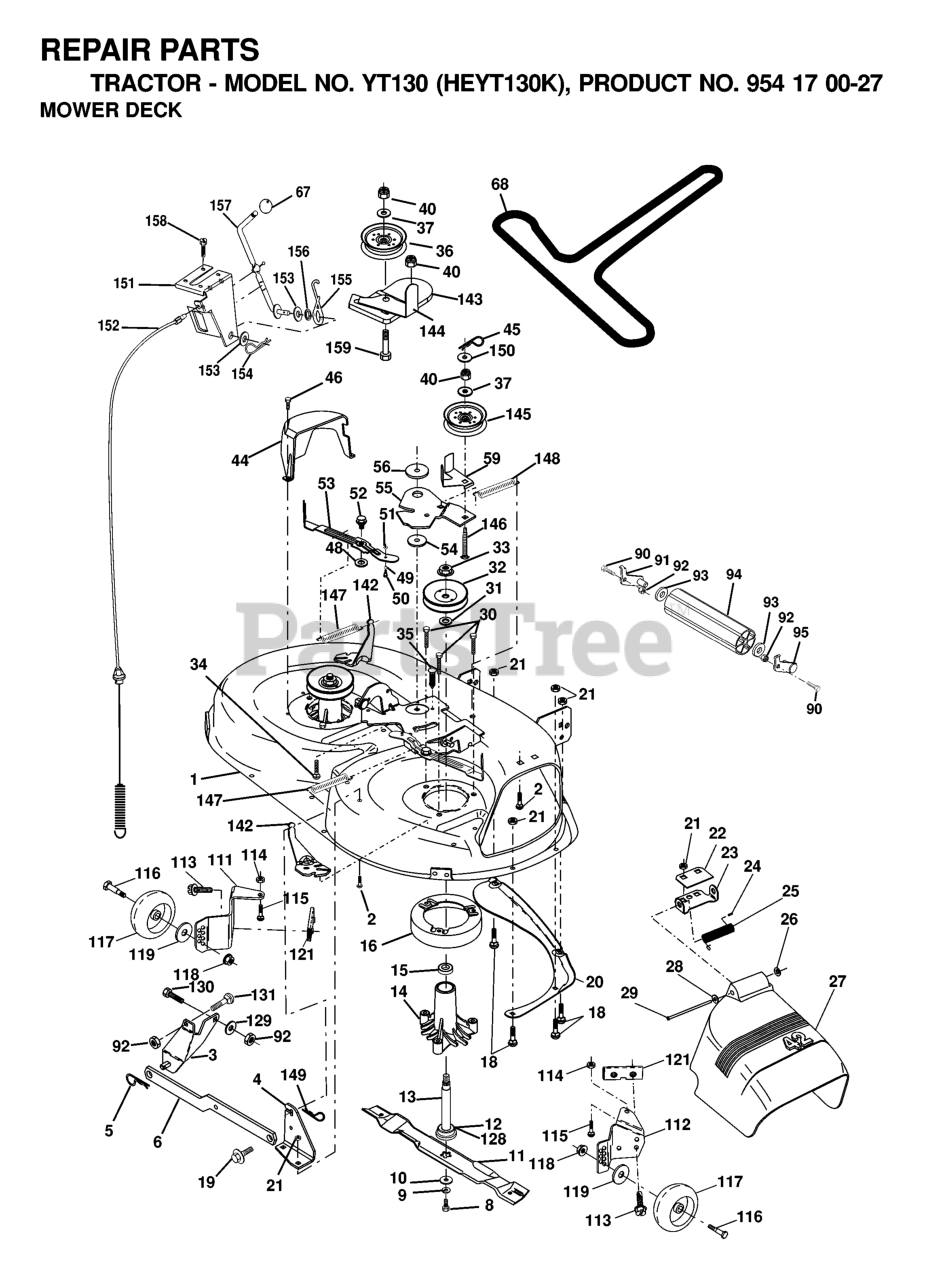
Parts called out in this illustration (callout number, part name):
1	Gear Cover
2	RING-RETAINING-EXT .438 X .035
3	SCRW TPNG 12-24X.50 HX WSHR HD
4	WASHER-FLAT STL .520X.827X.062
5	WASHER FLAT STL .531X1.00X.063
6	IDLER GEAR
7	BEARING BALL .50 X 1.38 X .437
9	IDLER SHAFT
10	DIFFERENTIAL ASSEMBLY
11	BEARING-BALL .625X1.382X.50
12	GEAR PINION
13	BEARING BALL .562X1.315X.437
14	DRIVE MOUNT
15	SPRING TENSION .051X.60X2.25
16	DRIVE ACTUATOR WELDMENT
17	PIVOT CHANNEL WELDMENT
18	NUT-LOCKING-CENTER .31-18
19	WASHER-FLAT STL .344X.688X.065
20	BOLT RD HD SQ NECK .31-18X.62
22	WASHER FLAT STL 1.390X2.00X.20
24	PIN ROLL .125 X .50
25	SHIFT LINK
26	SHIFT ARM WELDMENT
27	RETAINER PLATE
29	PIN ROLL .188 X .88
30	THRUST PLATE
31	Screw-Tapping 10-24 x .375 Hex Washer Head (580 R, 580 RS, 580 RSE, 580 RSW, 580 BBC)
32	GUIDE PLATE
33	FRICTION WHEEL ASSEMBLY
34	Nut-Hex .31-18
35	Washer-Locking .312 x .097 Heavy (600 C)
36	Washer Flat-Steel .328 x .875 x .062
37	FRICTION SHEAVE
38	BEARING BALL .625X1.375X.43
39	WSHR FLT STL 1.062X1.344X.032
40	SPINDLE BEARING
41	BEARING RETAINER
42	Bolt-Round Head Square Neck .31-18 x 1.75 Grade 5 (600 C)
43	RING-RETAINING EXT .625 X .035
44	FRICTION RING
45	FRICTION WHEEL HUB
46	SCRW TPNG 12-24X.50 HX WSHR HD
47	Bolt-Hex .25-20 x .50 Grade 5 (600 C)
48	FRICTION WHEEL
49	FRICTION DISC
50	NUT-LOCKING-CENTER .25-20
51	Bearing Plate (600 C)
52	Bearing Retainer (600 C)
53	BEARING BALL 1.00 X 2.00 X .56
54	Bearing Retainer (600 C)
55	Ring-Retaining - External 1.00 x .042 (600 C)
56	Fitting-Lube .25-28 x .256 (580 RSW, 600 C)
